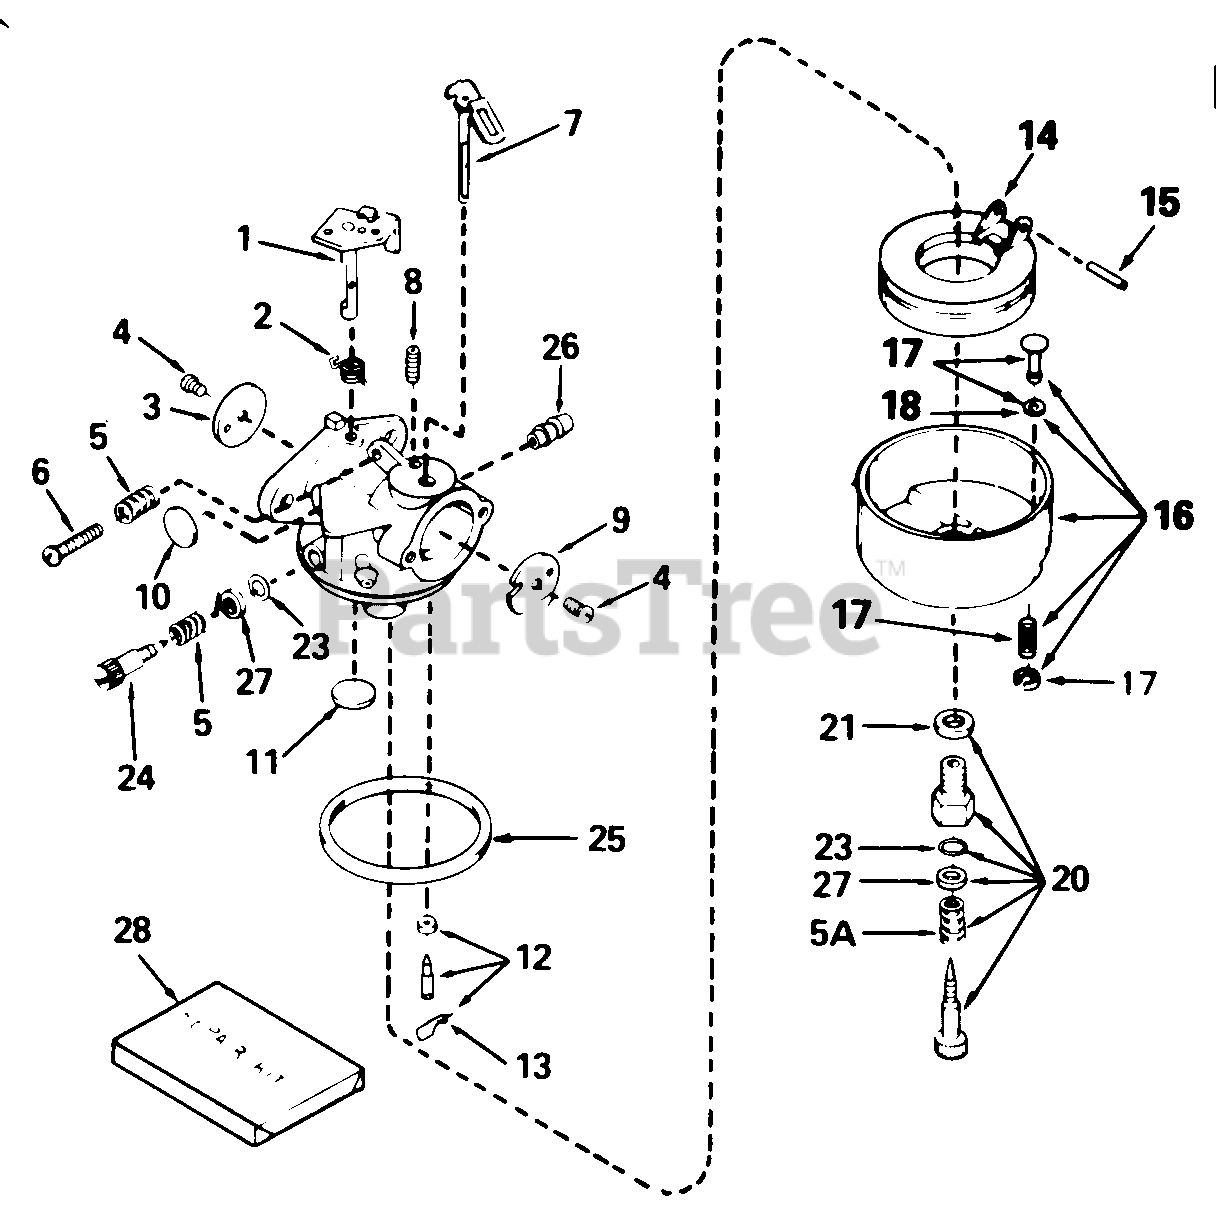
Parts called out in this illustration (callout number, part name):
1	Shaft & Lever Ass'y., Throttle
2	Spring, Throttle Return
3	Shutter, Throttle
4	Screw, Throttle & Choke Shutter
5	Spring, Regulating Screw
5A	Spring, Main Adjustment Screw
6	Screw, Idle Regulating
7	Shaft & Lever Ass'y., Choke
8	Spring, Choke Positioning
9	Shutter, Choke
10	Plug, Welch
11	Plug, Welch
12	Inlet Needle, Seat & Clip Ass'y.
13	Clip, Inlet Needle
14	Float, Carburetor
15	Shaft, Float
16	Bowl, Float
17	Plunger Ass'y., Drain
18	Gasket, Drain
20	Adjustment Screw Ass'y., Main
21	Gasket, Bowl-to-Body
23	"O"-Ring, Adjustment Screw
24	Screw, Idle Adjustment
25	Gasket, Bowl-to-Body
26	Fitting, Fuel Inlet
28	Repair Kit
